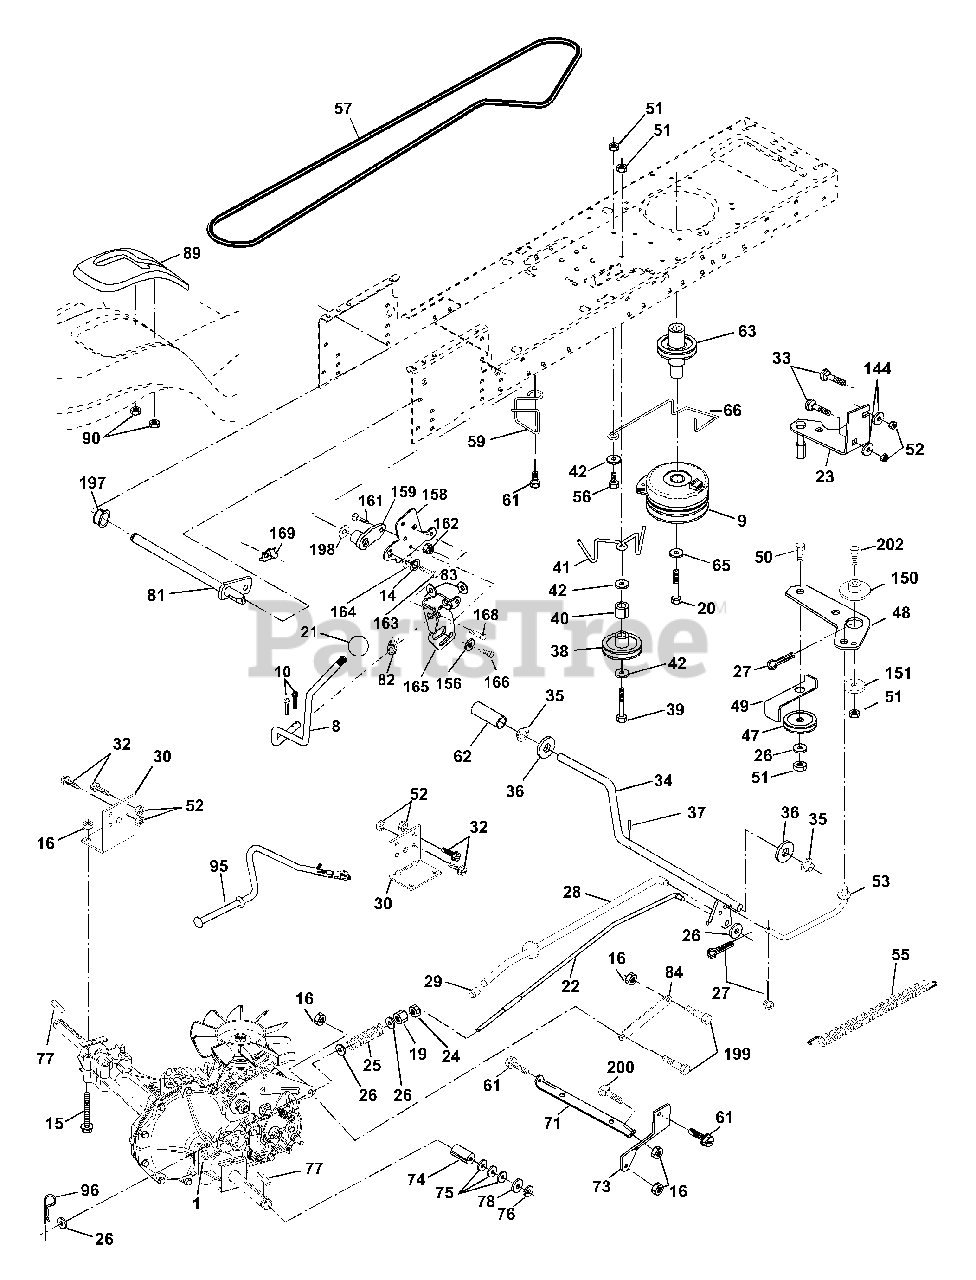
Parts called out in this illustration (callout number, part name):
1	Transaxle
8	Rod Shift Fender Adjust STLT
9	Clutch, Elect. EVX LT Mag 5217-2
10	Pin Cotter 1/8 x 1 CAD
14	Washer Lock Hvy Helical
15	Bolt, Hex Flghd 5/16-18 Gr. 5
16	Nut Lock Hex W/Ins. 5/16-18 Unc P
19	Nut Lock Hex W/Wsh 3/8-16 Unc
20	Bolt Hex 7/16-20 x 4-1/4 Ga. 1.38
21	Knob, Duckhead 1/2-13
22	Rod, Brake Hydro
23	Bracket, Asm Anti-Rot EVX
24	Nut
25	Spring, Brake Rod
26	Washer
27	Pin Cotter 1/8 x 3/4 CAD.
28	Rod, Parking Brake
29	Cap, Parking Brake
30	Bracket, Transaxle
32	Bolt Hex Hd 5/16-18 Unc x 3/4
33	Bolt Rdhd Sqnk 5/16-18 UNC x 3/4
34	Shaft, Foot Pedal
35	Bearing, Nylon
37	Pin, Roll
38	Pulley, Idler, Flat
40	Spacer, Split
41	Keeper, Belt Idler
42	Washer 13/32 x 13/16 x 12 Gauge
47	Pulley, Idler, V-Groove
48	Bellcrank Clutch Grnd Drv Stl
49	Retainer, Belt
52	Nut Crownlock 5/16-18
53	Link, Clutch
55	Spring, Return, Clutch
56	Bolt Fin Hex 3/8-16 UNC x 1-1/4
57	V-Belt, Ground Drive
59	Keeper, Center Span
61	Screw 3/8-16 x 3/4
62	Cover, Pedal
63	Pulley, Clutch Electric EVX
65	Washer
66	Keeper Belt Engine Hydro
71	Strap Torque Lh Hydro
73	Strap Torque Rh Hydro
74	Spacer, Axle
75	Washer 25/32 x 1-1/4 x 16 Gauge
77	Key, Square
78	Washer 25/32 x 1-5/8 x 16 Gauge
81	Shaft Asm Cross Tapered
82	Spring Torsion
83	Washer 17/32 x 3/4 x 16 Ga.
84	Link Transaxle Hydr
89	Console, Shift
90	Nut, Self-Thd Wsh-hd 1/4 Zinc
95	Control Asm Bypass Hydro
96	Retainer Spring 1" Zinc/Cad
144	Washer 11/32 x 5/8 x 16 Ga.
150	Bushing Bellcrank Grd Drive
151	Washer 13/32 x 2 x 10 Ga.
156	Washer Srrted 5/16ID x 1.125
157	Bolt Shoulder 5/16-18 Unc - 2A
158	Bracket Shift Mount
159	Hub Tapered Flange Shift Lt
161	Bolt Rdhd Sqnk 1/4-20 Unc
162	Nut Crownlock 1/4-20 Unc
163	Bolt Hex Fin 1/4-20 Unc x 1 Gr 5
164	Washer 5/8 x 0281 x 10 Ga
165	Bracket Pivot Lever
166	Screw 5/16-18 x 5/8
168	Bolt Shoulder 5/16-18 x .561
169	Plate Fastening Cross Sh STLT/CRD
197	Nyliner Snap-In 5/8" ID
198	Washer Nyl 7/8 ID x .105" Hyd
199	Bolt Shoulder 5/16-18 Unc
200	Bolt Rdhd Sq Neck 5/16-18 x 1 Unc
201	Screw Thdrol 3/8-16 x 3/4 TYTT
